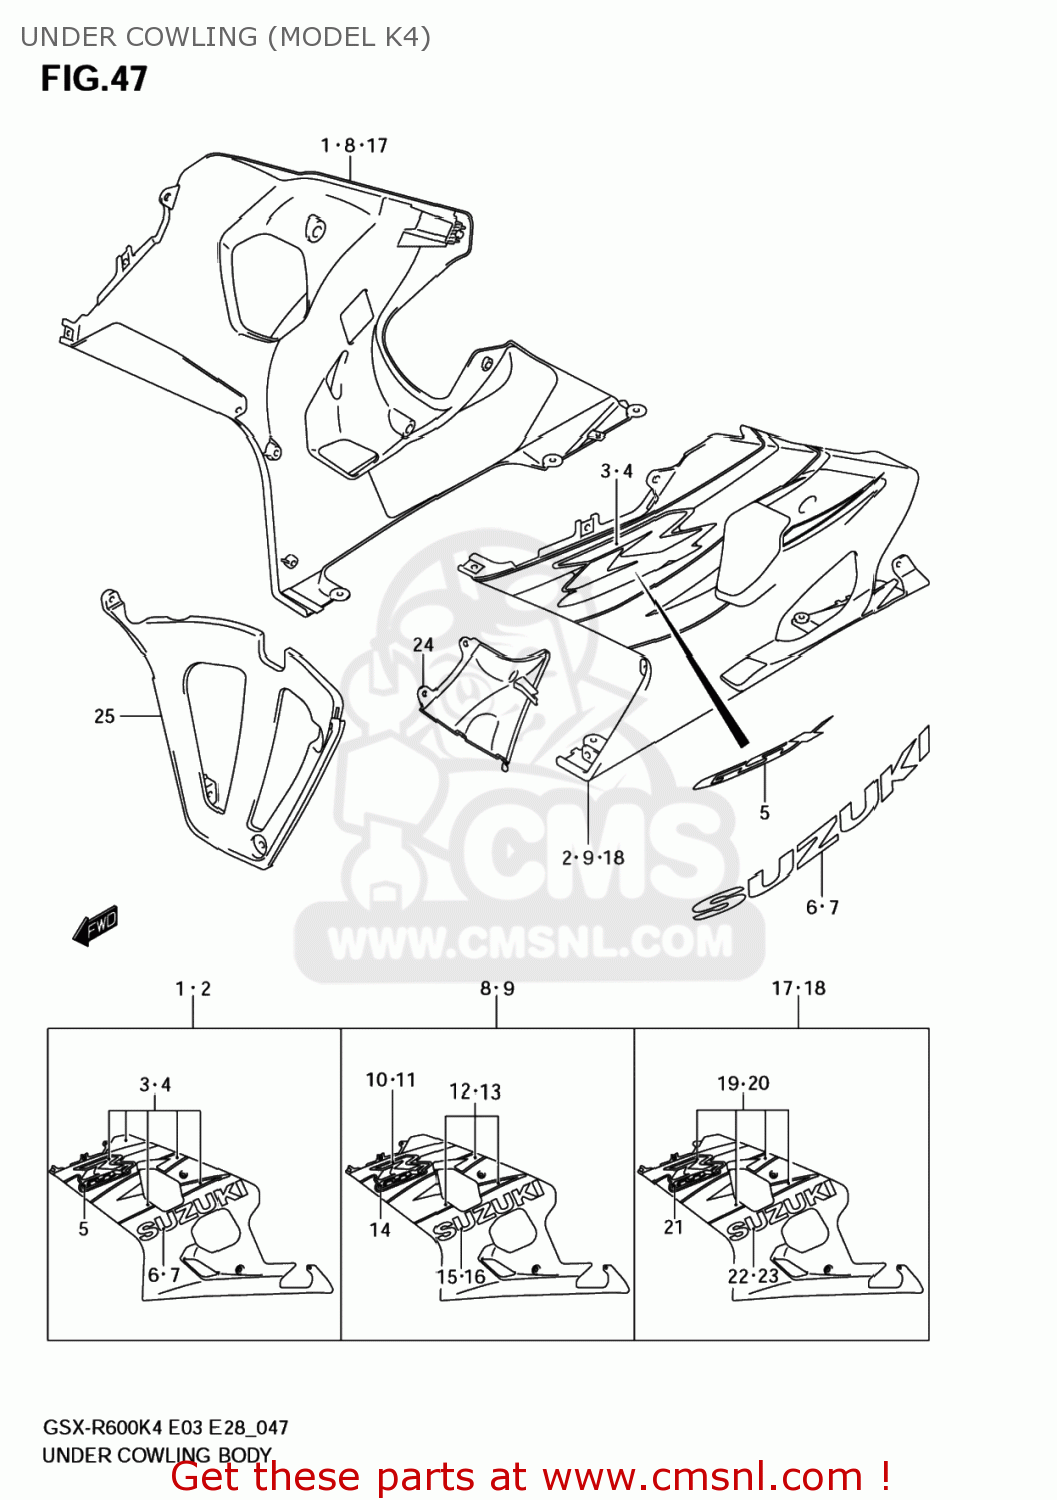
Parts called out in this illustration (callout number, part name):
1	COWLING ASSY,UNDER,R
2	COWLING ASSY,UNDER,L(BLUE)
3	TAPE,COWL UNDER,R
4	TAPE,COWL UNDER,L
5	EMBLEM,GSX
6	EMBLEM,R
7	EMBLEM,L
8	COWLING,UNDER,R
9	COWLING ASSY,UNDER,L(YELLOW)
10	TAPE,COWL UNDER
11	TAPE,COWL UNDER
12	TAPE,COWL UNDER,R
13	TAPE,COWL UNDER,L
14	EMBLEM,GSX
15	EMBLEM,R
16	EMBLEM,L
17	COWLING,UNDER,R
18	COWLING ASSY,UNDER,L(BLACK)
19	TAPE,COWL UNDER,R
20	TAPE,COWL UNDER,L
21	EMBLEM,GSX
22	EMBLEM,R
23	EMBLEM,L
24	COWLING,UNDER INNER,L
25	COWLING,UNDER CTR
